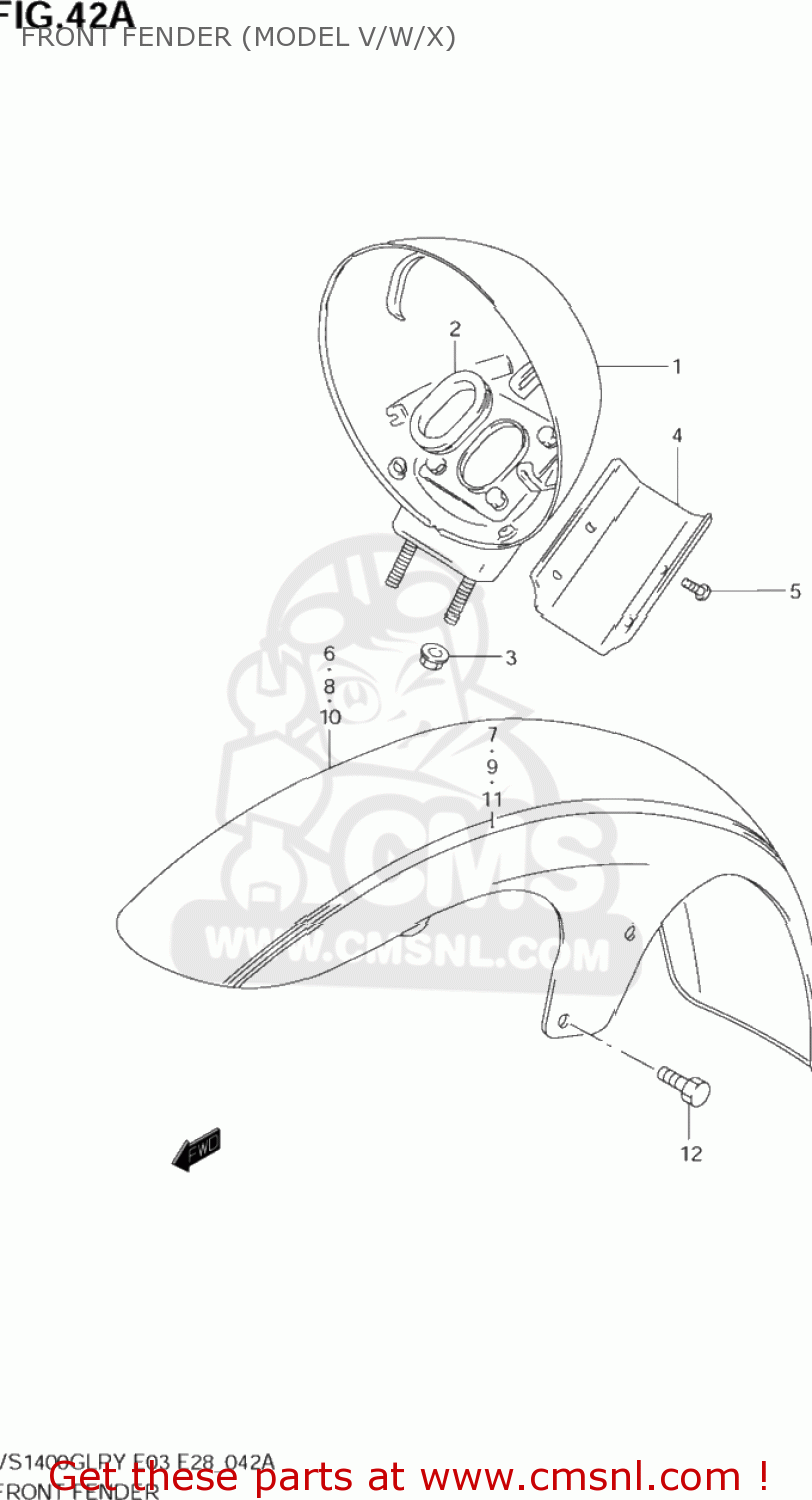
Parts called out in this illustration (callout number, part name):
1	HOUSING,HEADLAMP
2	GROMMET
3	NUT
4	COVER,HEADLAMP HSG
5	SCREW
6	FENDER ASSEMBLY,FRONT
7	TAPE SET,FRONT FENDER
8	FENDER ASSEMBLY,FRONT
9	TAPE SET,FRONT FENDER
10	FENDER ASSEMBLY,FRONT
11	TAPE SET,FR FENDER STRIPING
12	BOLT
